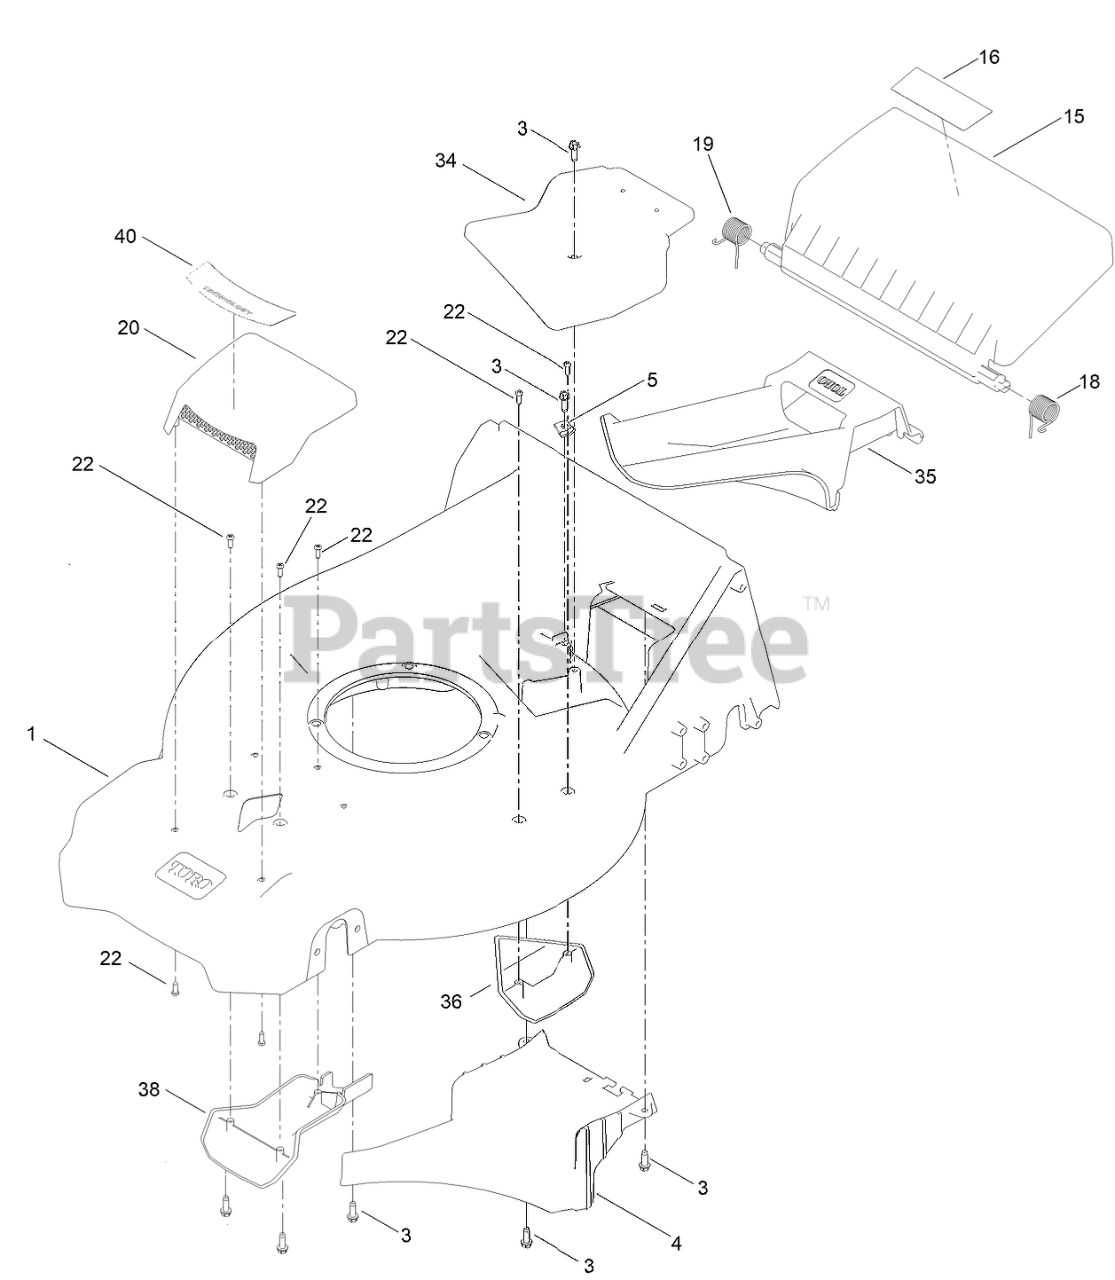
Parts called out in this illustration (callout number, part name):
1	HOUSING ASM
3	SCREW-HWHTF
4	RAMP-DISCHARGE
5	CLAMP-CABLE
15	DOOR-REAR
16	DECAL-WARNING
18	SPRING-TORSION, LH
19	SPRING-TORSION, RH
20	ASM-COVER, TOP INTAKE
22	SCREW-PLASTIC, PPH
34	COVER-BELT, TOP
35	PLUG-MULCH
36	KICKER-HOUSING
38	COVER-INTAKE, BOTTOM
40	DECAL-COVER, INTAKE
